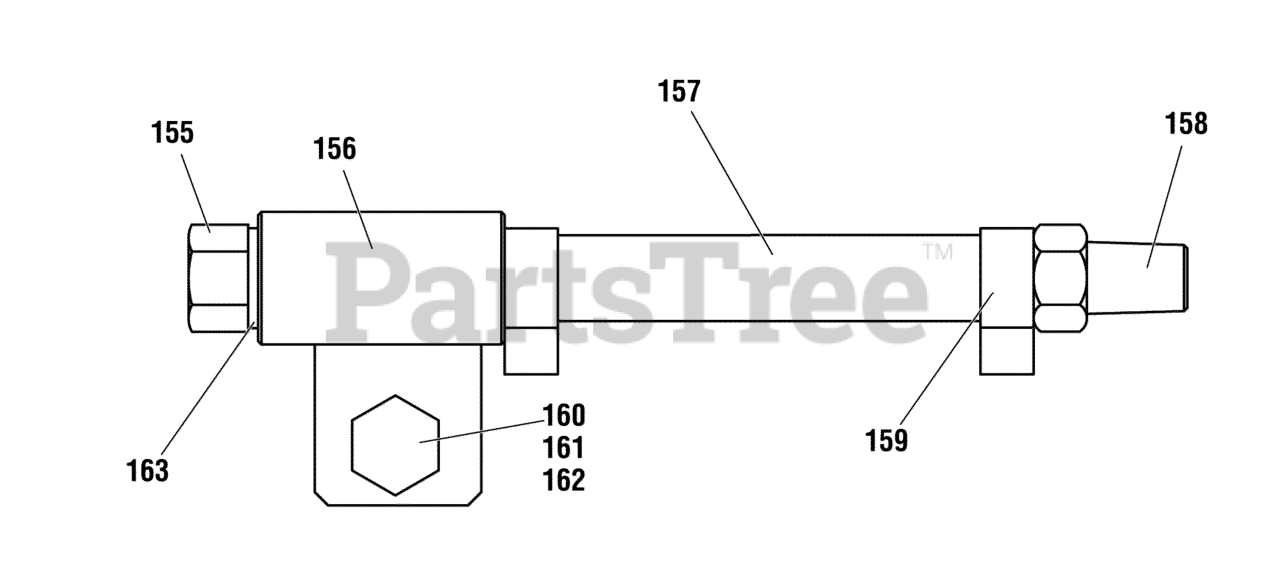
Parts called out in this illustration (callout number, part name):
155	PLUG, Hex Head
156	NOZZLE
158	TAPER JOINT
159	SPRING CLAMP
160	BOLT, Hex Head, M8 x 20
161	WASHER, Spring, 8
162	NUT, Hex Lock, M8
163	GASKET, Sealing, 14
